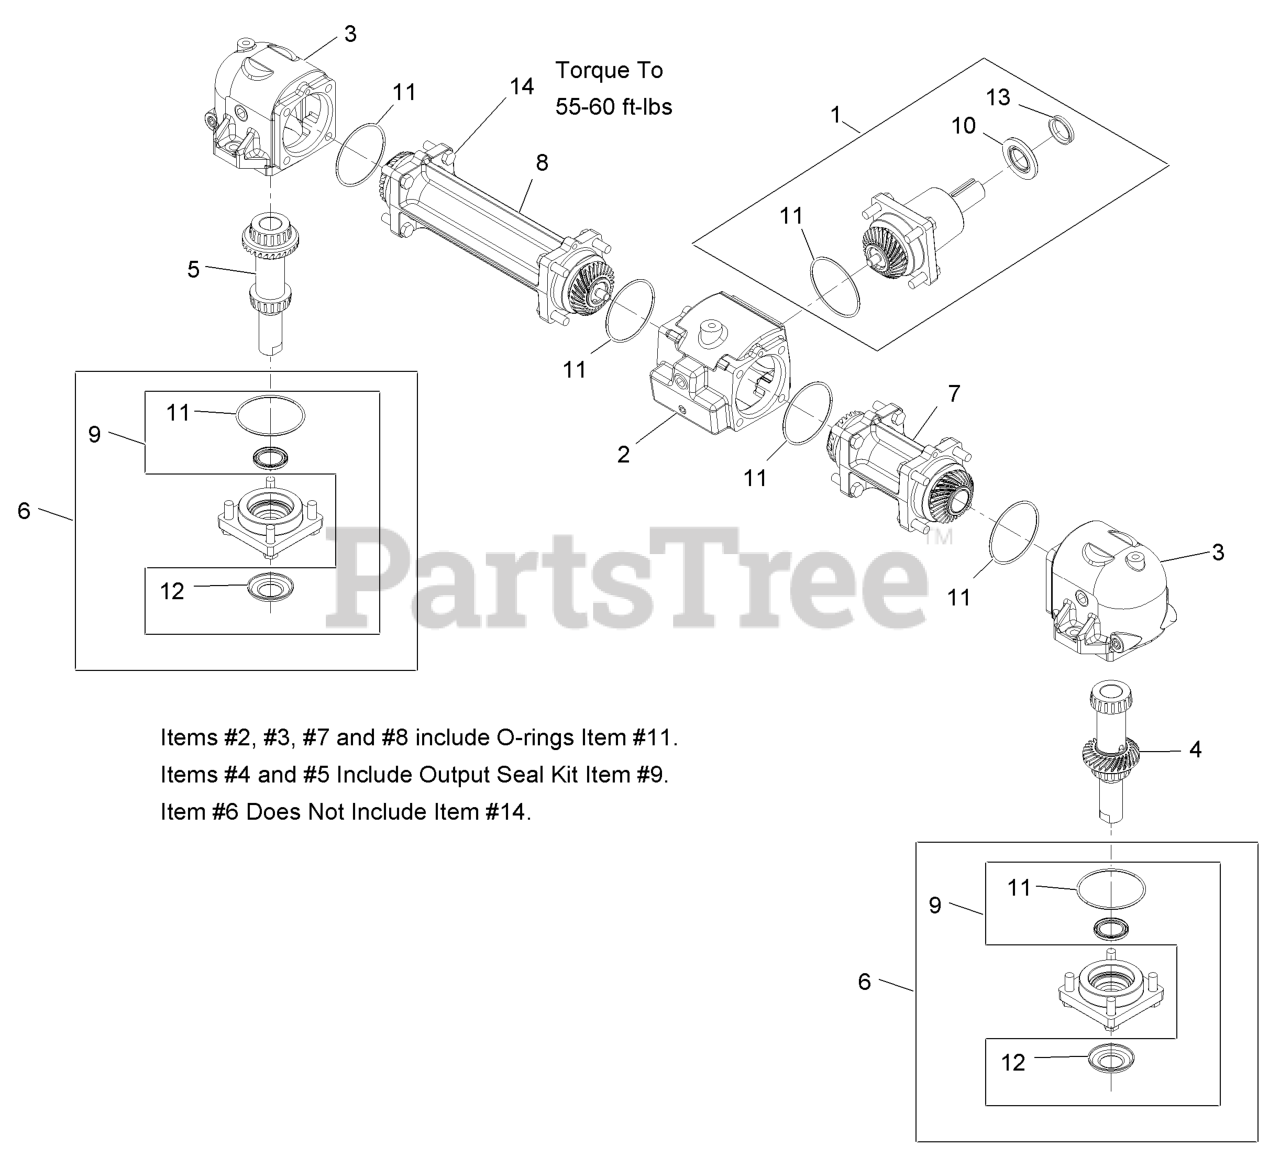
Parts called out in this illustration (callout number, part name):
1	INPUT PINION ASM
1	PINION-INPUT
2	HOUSING-CENTER
3	HOUSING-END
4	OUTPUT SHAFT AND GEAR-LH
5	OUTPUT SHAFT AND GEAR-RH
6	CAP-OUTPUT
7	TUBE-CONNECTOR, SHORT
8	CONNECTOR-TUBE, LONG
9	OUTPUT SEAL KIT
10	SEAL-INPUT
11	SEAL-O-RING
12	WASHER-CUPPED
13	SEAL-V-RING
